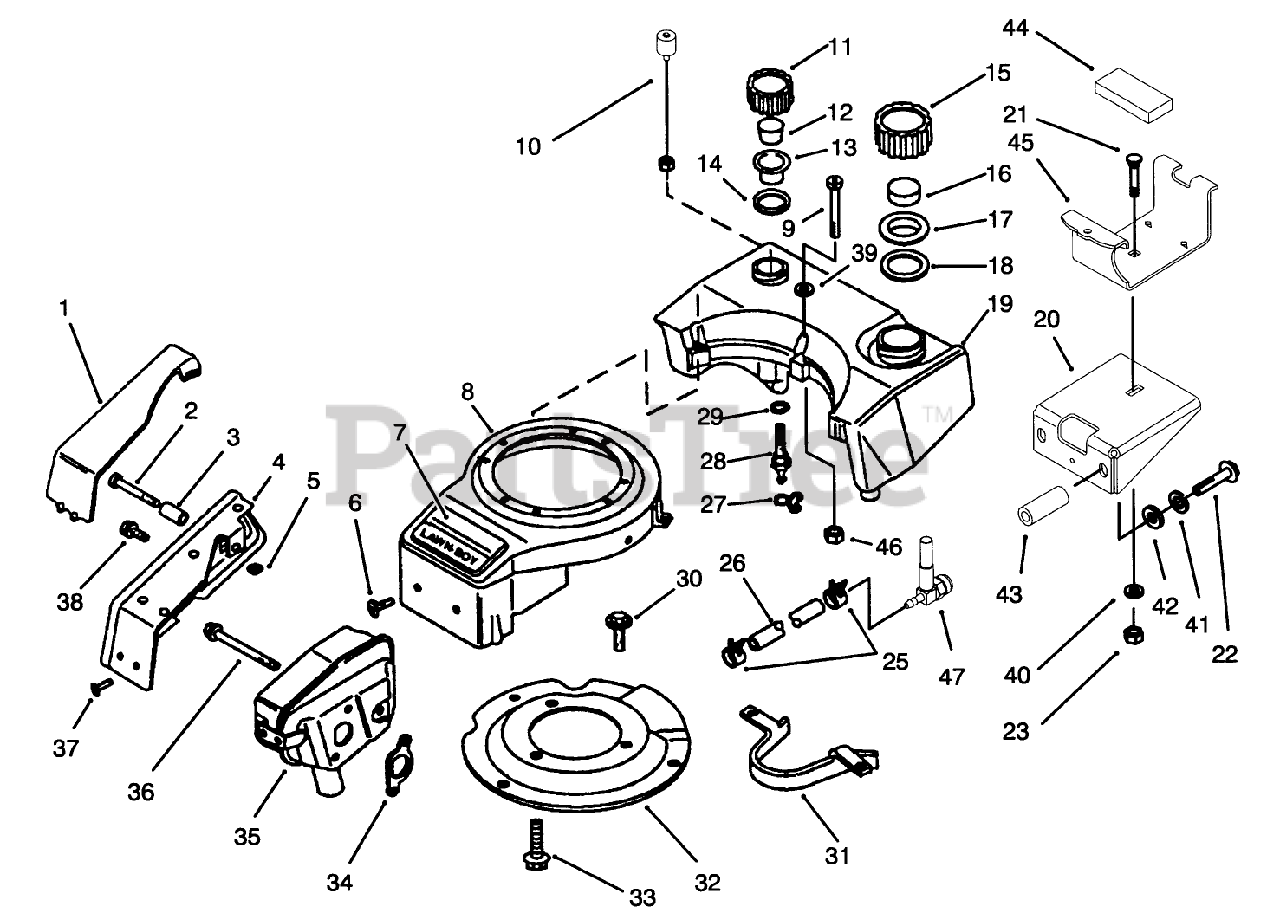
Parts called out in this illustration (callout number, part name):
1	COVER MUFFLER CP
2	SCREW SM
3	SPACER S
4	MUFFLER GUARD AY
5	NUT-PUSH
7	APPLIQUE SM
9	SCREW-PPH
10	OIL SWITCH AY S
11	CAP AY. OIL M
15	CAP AY - FUEL M
16	BAFFLE - FOAM SM
17	COVER-FUEL CAP F
18	GASKET-FUELCAP SM
21	SCREW-CARR
22	SCREW-HSH
23	NUT-HEX
24	DISC/LB SER.BUL.#6
25	HOSE CLAMP SM
26	GAS LINE SM
29	O-RING SM
30	SCREW-HH
32	PLATE SM
34	GASKET - EXH SM
36	SCREW-SEMS
37	SCREW SM
38	SCREW S
39	WASHER-FLAT
40	WASHER-FLAT
42	WASHER-FLAT
43	SPACER SM
45	STRAP,FUELTANK SM
46	NUT-LOCK, NI
